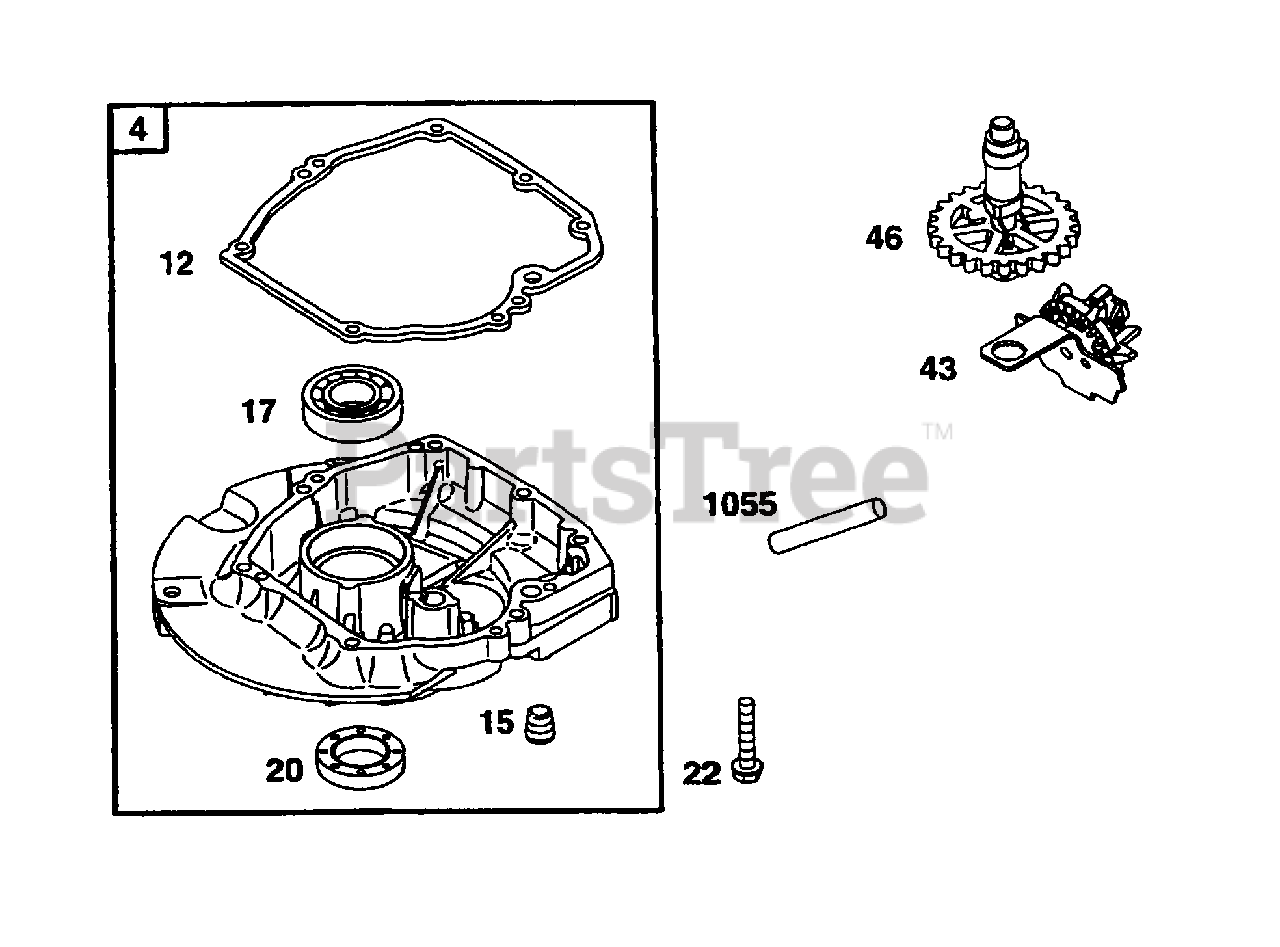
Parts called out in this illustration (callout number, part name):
4	Engine Sump
12	Crankcase Gasket
15	Oil Drain Plug
17	Ball Bearing
20	Oil Seal
22	Screw Hex
43	Governor Oil Slinger
1055	Oil Pump Tube
